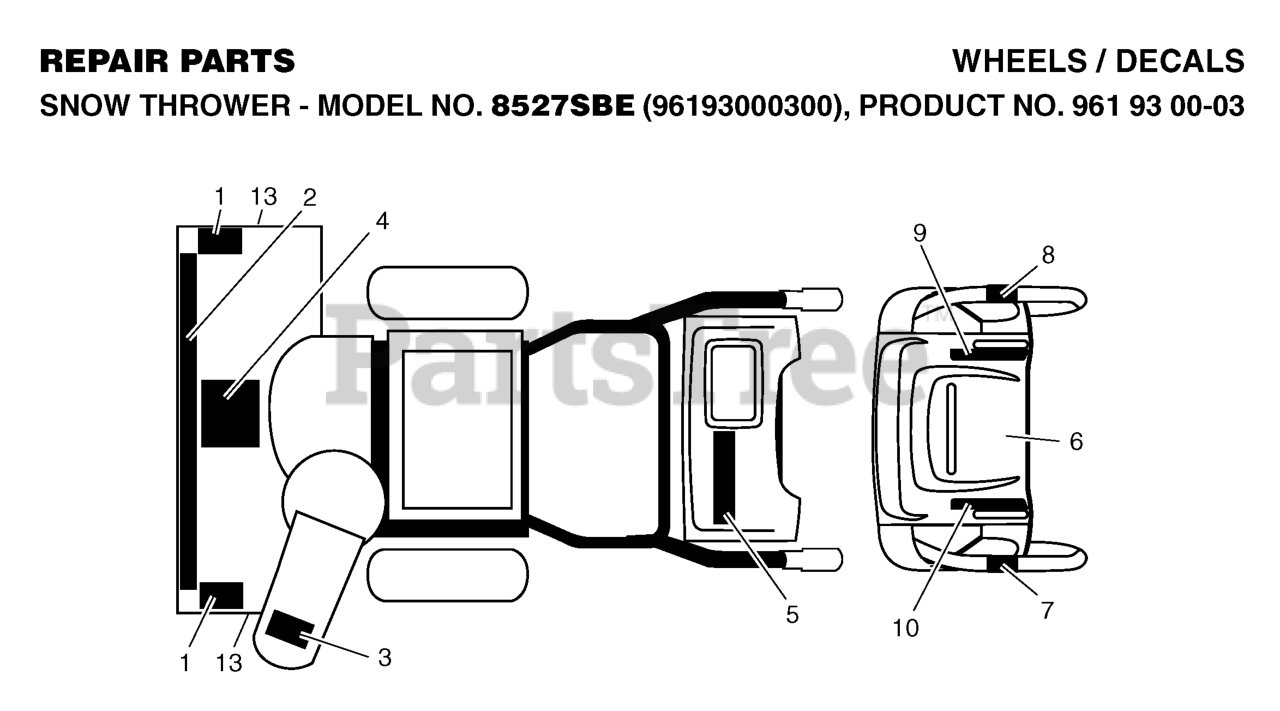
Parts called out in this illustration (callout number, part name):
1	DECAL DANGER
3	DECAL, DANGER DEFLECTOR
4	DECAL, DANGER
5	DECAL.CONSOLE.PANEL.927SBE
6	DECAL.SNOWTHROWER.CONSOLE.INST
7	DECAL.TRACT.ASM.ENG.CLUTCH.K
8	DECAL, AUGER LEVER
9	DECAL, SPEED CONTROL
10	DECAL, REMOTE DEFLECTOR
13	DECAL, HUSQVARNA
